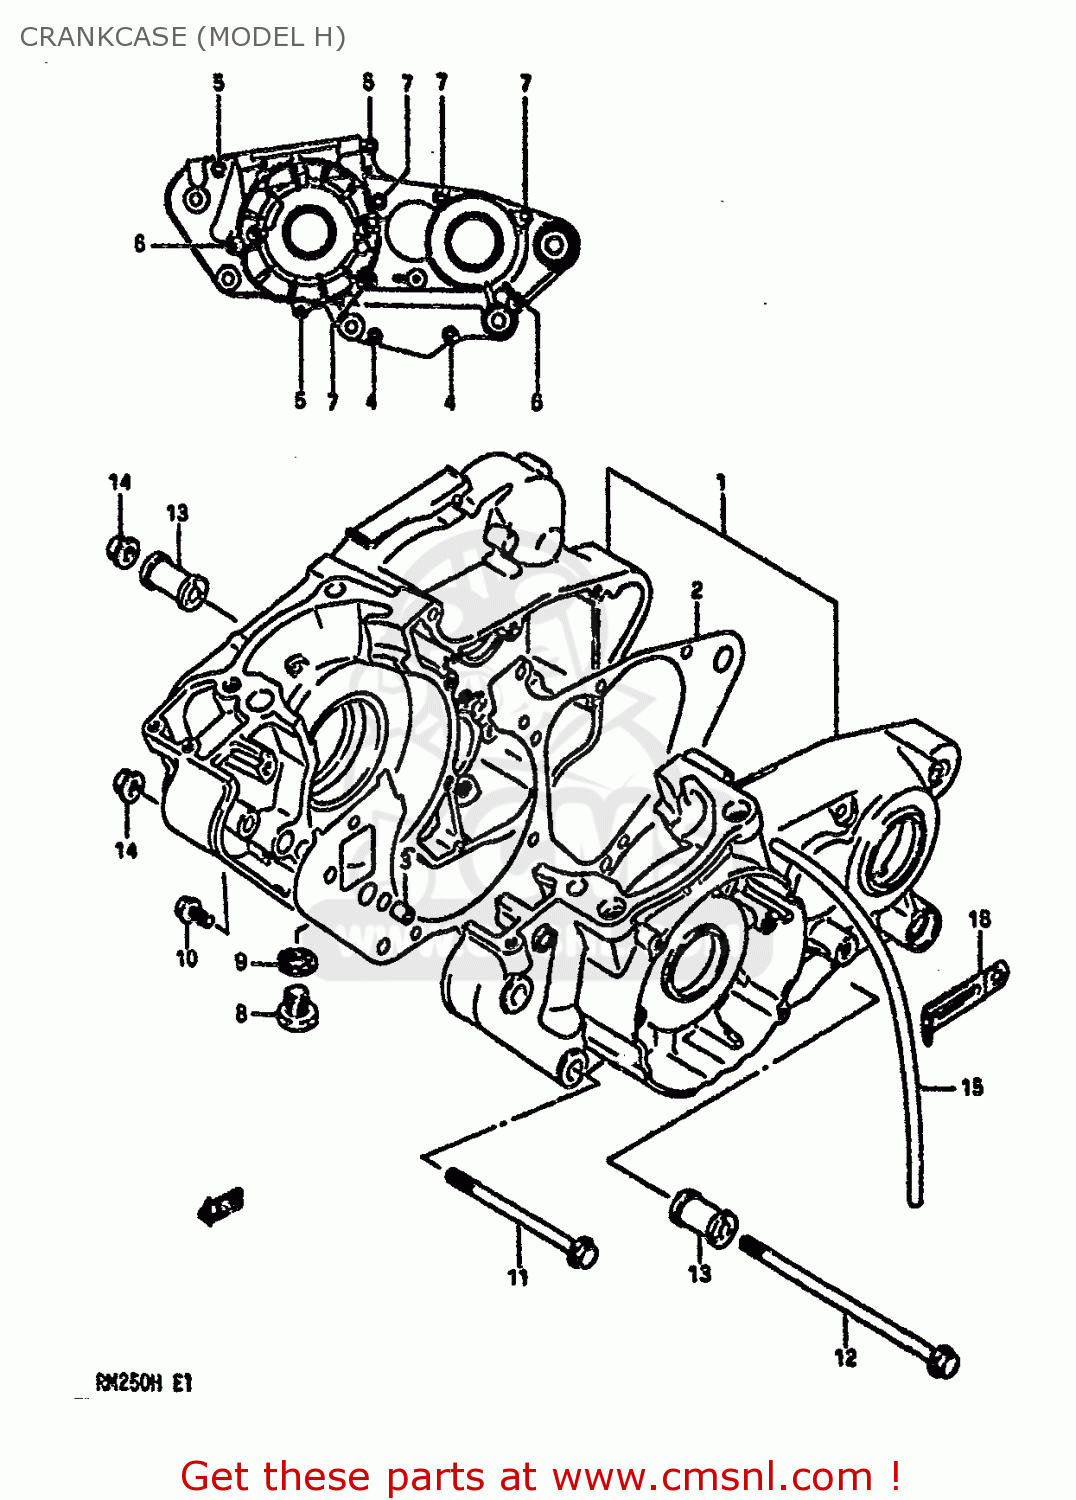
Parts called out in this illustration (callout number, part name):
1	CRANKCASE SET
2	GASKET,CRANKCASE (MCA)
3	PIN
4	SCREW
5	SCREW
6	SCREW
7	SCREW 6X60
8	PLUG
9	GASKET(14X19.2X2) (NAS)
10	SCREW (6X10)
11	BOLT(8X100)
12	BOLT
13	SPACER,ENGINE MOUNT(L:32)
14	NUT
15	HOSE
16	CLAMP
